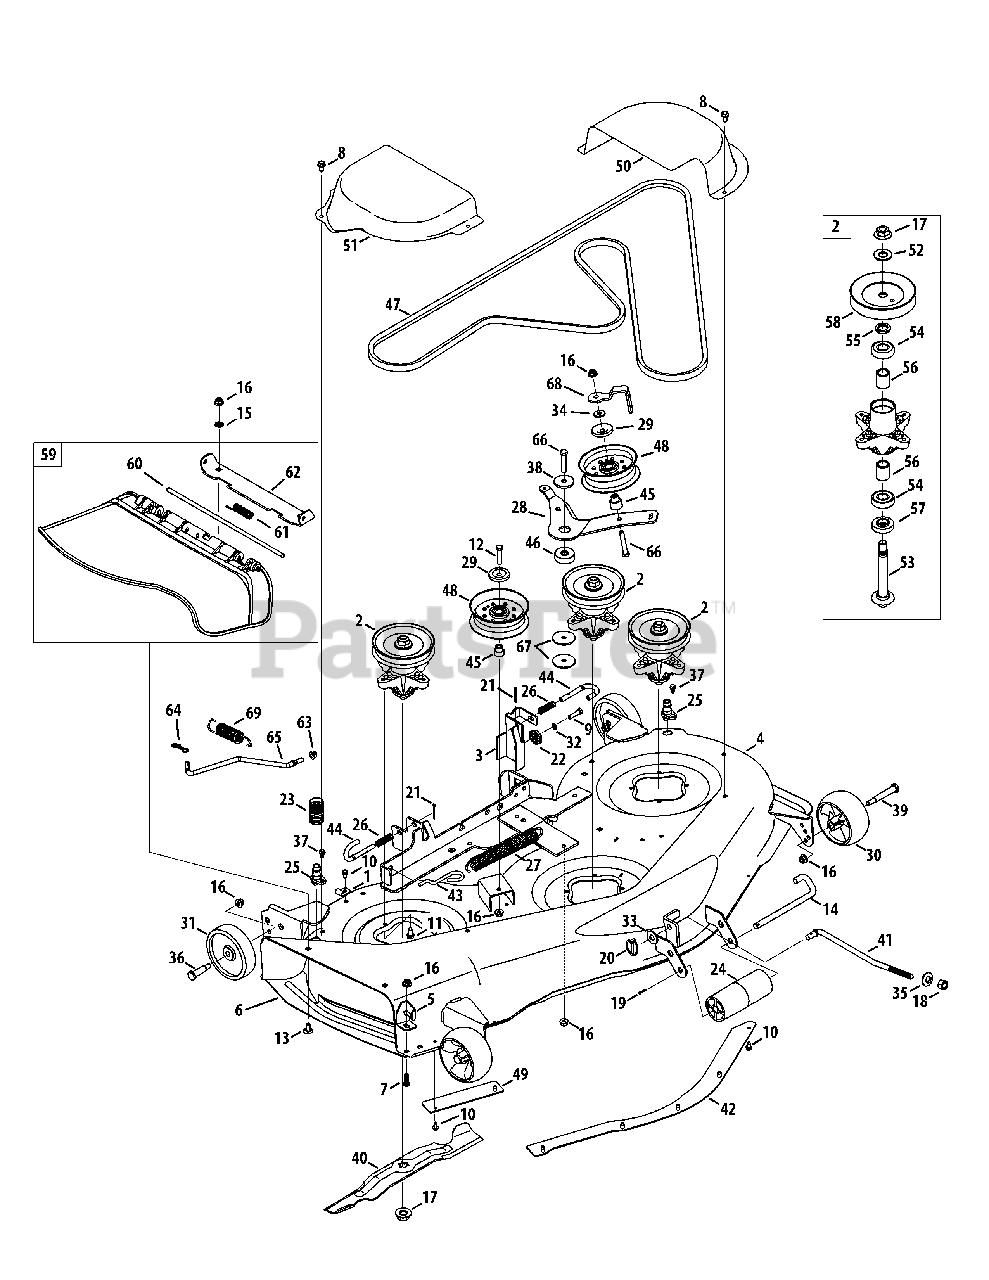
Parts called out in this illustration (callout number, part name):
1	Bracket, Hook, Retainer
2	Spindle Assembly, Pulley, 5.39 Dia.
3	Bracket Assembly, Deck, Hanger LH
7	Hex Screw, 3/8-16, 1.00, Gr5, Spec
8	Screw, Self-tapping, 5/16-18, .750,
9	Hex Screw, 5/16-18, 1.25, Gr5, Std
10	Screw, Self-tapping, 1/4-20, 0.500
11	Screw, Self-tapping, 5/16-18, 0.750,
12	Hex Screw, 3/8-16, 2.00, Gr5, Std
13	Bolt, Carriage, 3/8-16, 0.75, Gr1
14	Roller Pin-1/2 Dia. x 7.31
15	Nut, Push, 3/8
16	Nut, Flange Lock, 3/8-16, Nylon
17	Nut, Flange, 5/8-18
18	Nut, 1/2-13
19	Pin, Cotter, 3/32, 1.0
20	Pin, Lynch, .1875
21	Pin, Cotter, 1/8 x 1.25
22	Gear, Deck, Adjustment
23	Coupler, Water
24	Roller, Front
25	Deck Wash Nozzle
26	Spring, Compression .535 OD x 1.751
27	Spring, Extension, 1.25 OD x 8.5
28	Pivot Idler bracket
29	Pulley Cap
30	Wheel, Deck, 5.0 Dia. Ball
31	Wheel, Deck 5.0 x 1.38
32	Washer, Lock, 5/16, Regular Duty
33	Washer, Flat, .531 x 1.25 x .100
34	Flat Washer, .385 x 1.00 x .135
35	Washer, Bell, .63 x 1.25 x .18
36	Bolt, Shoulder, .496 x 1.525, 3/8-16
37	Shoulder Screw, 1/4-20 x 0.50
38	Shoulder Spacer, .970 x .190
39	Bolt, Shoulder, .496 x 2.50, 3/8-16
40	Blade, 17.90 Star 2 In 1
41	Rod, Lift, Deck, Front, 11.7
42	Skirt, Center, 50"
43	Rod, Deck Spring Hook
44	Rod, Deck Release
45	Shoulder Spacer
46	Spacer, .385 ID x 1.75 OD x .585
47	Belt, V-Type
48	Pulley, Idler, 4.50" Dia.
49	Skirt, RH, 50"
50	Cover, Belt, LH 50"
51	Cover, Belt, Rh 50"
52	Flat Washer, .760 x 1.50 x .120
53	Shaft, Spindle, 5.75
54	Bearing, Ball, .787id x 1.85 Od x .551
55	Spacer, .79 ID x 1.25 OD x .175
56	Spacer, .80 x 1.10 x 1.322
57	Spacer, .79 x 1.82 x .55
58	Pulley, Deck, 5.39 Dia.
59	Chute Assembly
60	Pin, Hinge, .3175 Dia. x 14.06 ,1
61	Spring, Torsion, .44 I.D. x 2.0,
62	Bracket, Chute 50/54"
63	Nut, Flange Lock, 5/16-18, Nylon
64	Pin, Cotter, Bow-Tie
65	Rod, Support, Deck (Tuff Torq)
66	Hex Screw, 3/8-16, 2.25, Gr5, Std
67	Flat Washer, .380 x 2.00 x .120
68	Idler Keeper
69	Spring, Extension, 1.15 OD x 5.99
